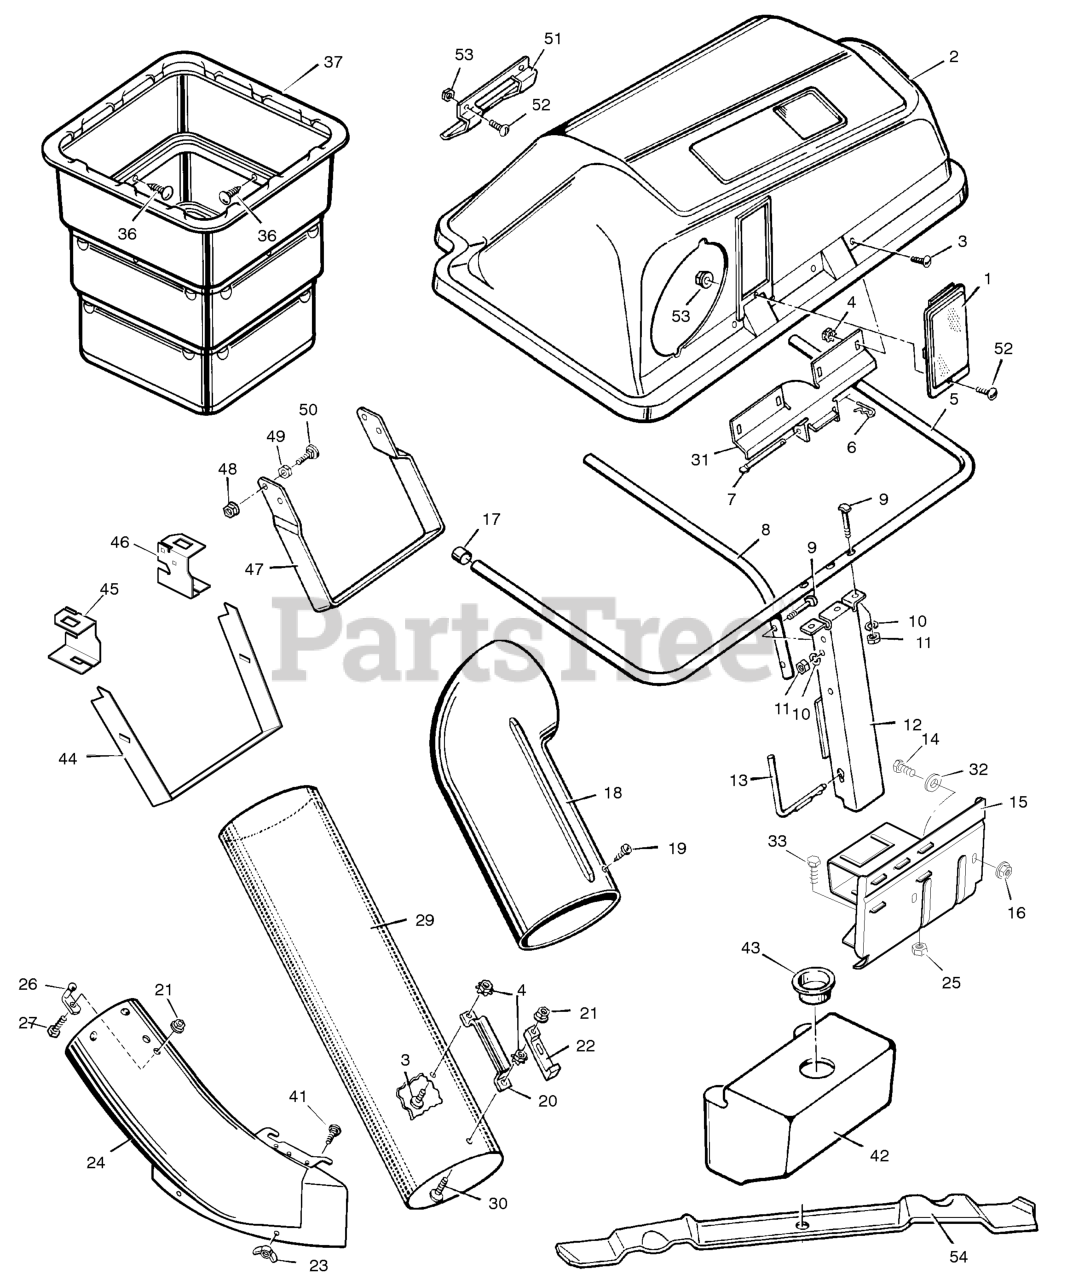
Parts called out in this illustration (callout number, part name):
4	Locknut
6	Pin, Hair
7	Pin, Hinge
8	Tube, Center
9	Bolt, Special
10	Lockwasher
11	Nut, Hex
12	Channel Assembly
13	Pin, Channel
14	CAPSCREW, Hex Head, 5/16-18 x 1
15	Mount Assembly, Bagger
16	Nut, Hex
17	Cap, End
20	HANDLE, Connect Tube
21	Locknut, Flange
22	Latch, Rubber
23	Wingnut
24	Tube, Extension
25	Hex Nut
26	Pin, Latch
27	Bolt, Carriage
29	Tube, Connector
31	Hinge, Cover
33	Bolt, Hex
36	Fastener, Plastic
37	Containers
41	Bolt, Carriage
42	Shell, Front Weight
43	Plug, Front Weight
44	Support, Weight (Type A)
45	Bracket, Right Hanger
46	Bracket, Left Hanger
47	Support, Weight (Type B)
48	Nut, Flange
49	Nut, Jam
50	Carriage, Bolt
51	Handle, Plastic
53	Nut, Hex
54	Blade, High Lift (76 cm)
